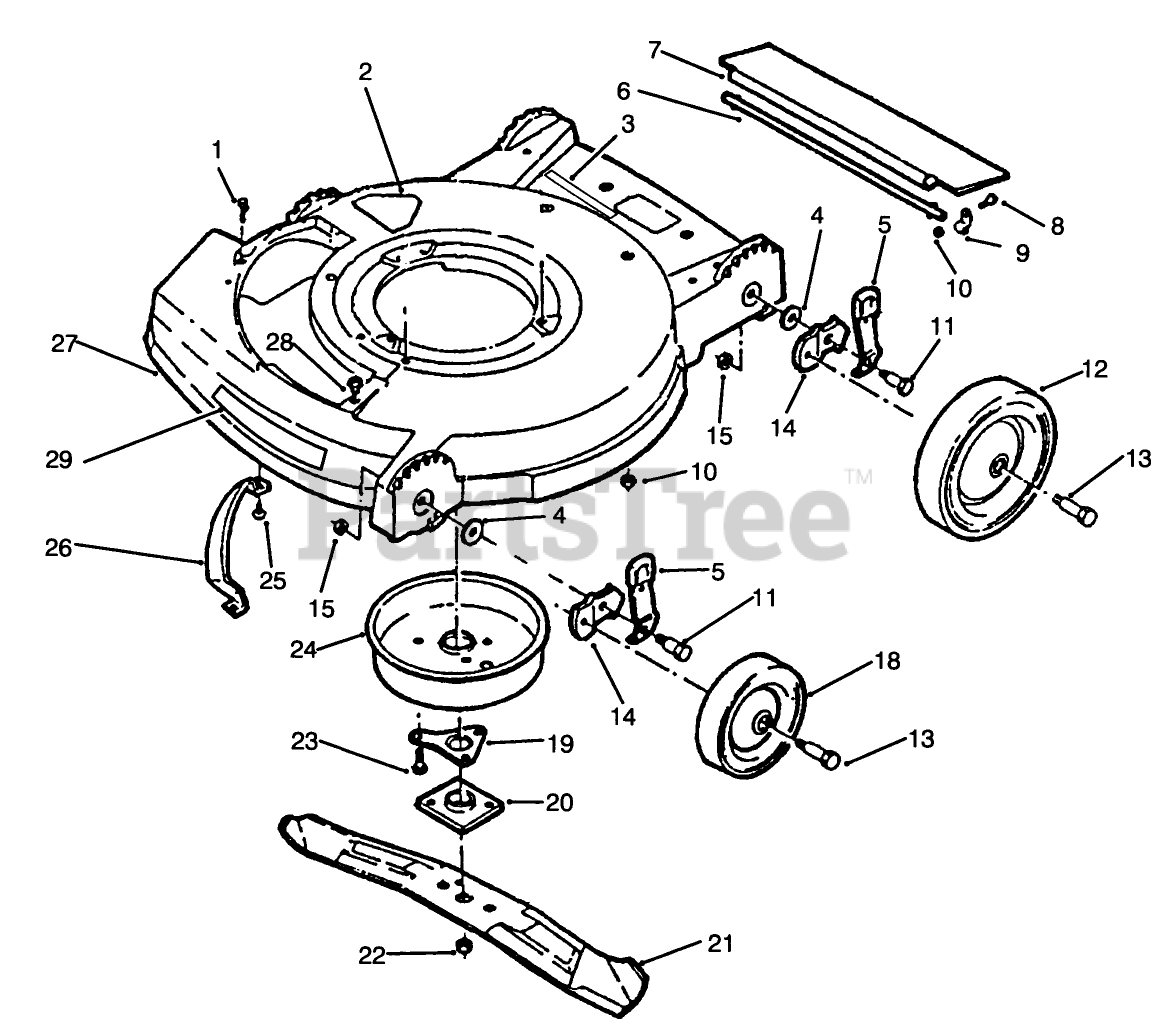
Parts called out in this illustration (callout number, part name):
1	SCREW-SEMS
2	DECAL-DANGER
3	DECAL - WARNING
5	SPRING ARM ASM
6	ROD 21" ADVANCE
7	T/SHIELD GEAUGA
9	CLAMP ROD KMC
10	NUT-LOCK, NI
12	8" WHEEL/TIRE ASM-GREY
13	BOLT-SHOULDER
15	NUT-LOCK, NI
19	SUPPORT F
20	PLATE AND COLLAR ASM
22	NUT-BLADE
24	MUFFLER COVER F
25	SCREW-HWH
26	BAR-TOE
